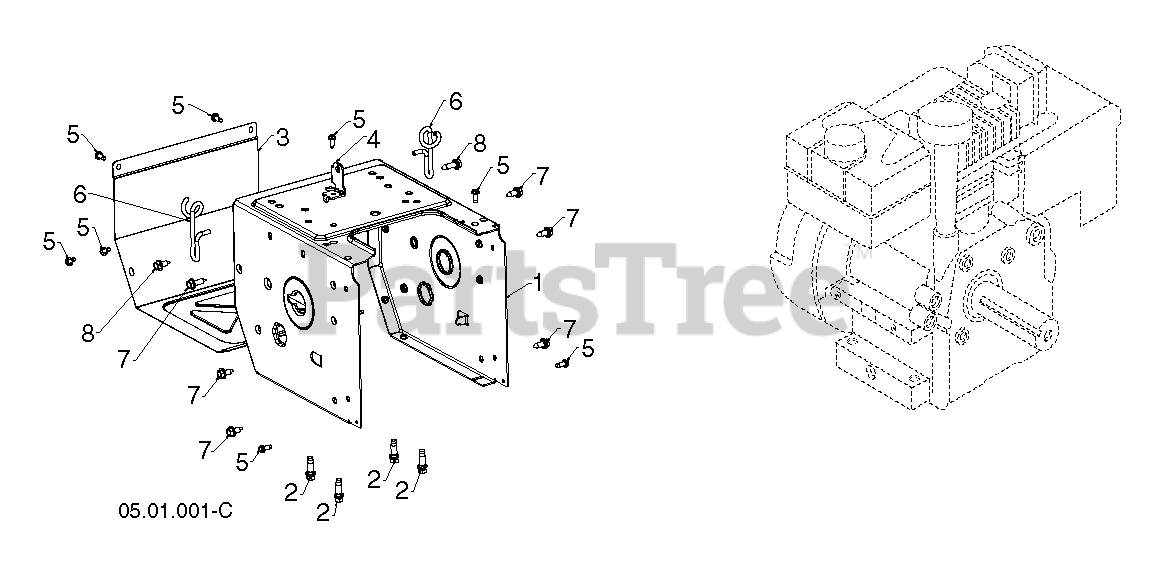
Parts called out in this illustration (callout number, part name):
2	BOLT 3/8-16X1-1/8
5	SCREW 14-20 X 5/8
6	RP.SUPPORT CABLES WIREFORM
7	BOLT.HEX.HD.WASHER.5/16-18X.75
8	Hex Washer Head Bolt, 5/16-18 X 3/4 Thread Forming
